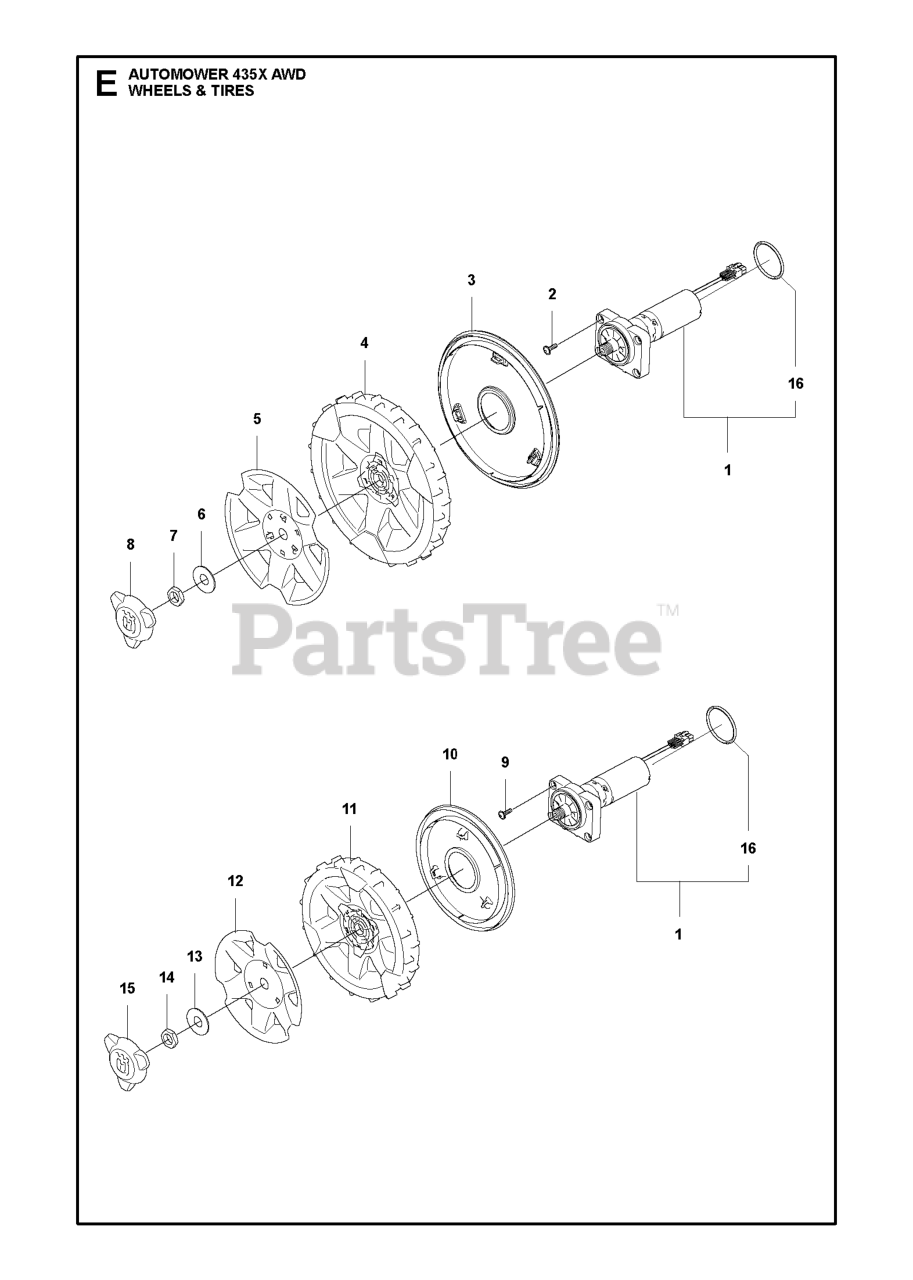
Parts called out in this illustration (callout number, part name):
2	SCREW ITXPANT
3	COVER REAR WHEEL
4	WHEEL SNAP FUNCTION ORANGE HVA
5	WHEEL COVER REAR WHEEL
6	WASHER WASHER REAR WHEEL 16X40
7	HEXAGON THIN NUT
8	HUB CAP REAR WHEEL NO CENTER P
9	SCREW ITXPANT
10	COVER REAR WHEEL
11	WHEEL ORANGE
12	WHEEL COVER PAINTED
13	WASHER WASHER REAR WHEEL 16X40
14	HEXAGON THIN NUT
15	HUB CAP REAR WHEEL NO CENTER P
16	O-RING LIGHT GREY
